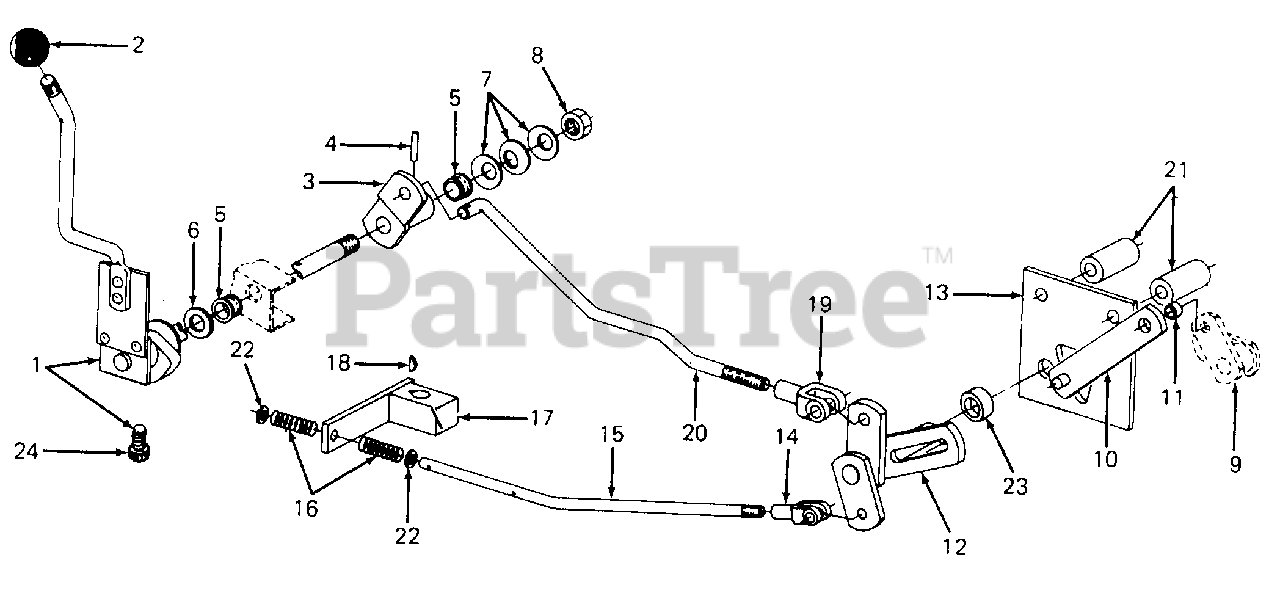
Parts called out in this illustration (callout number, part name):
1	Handle, Shifter Control
2	Knob, Shifter
3	Lever, Shifter
4	Pin, 3/16 X 1 Pln Slt-Spr
5	Bearing, Nyliner
6	Washer, Friction
7	Washer, .760 X 1.50 X .06 Belleville
8	Nut, 1/2 Cad P/T Lock GR 5
9	Control, Brake Link See Brake & Connections, Ref No. 4
10	Link, Actuator
12	Shaft, Hydro Control
13	Plate, Cam
14	Clevis, 5/16-24 X 2-1/4 Pln Lt Adj
15	Rod, Control
16	Spring, Compression
17	Arm Assy, Control Shaft
18	Key, 1/8 X 1/2 SAE 3 Woodruff
19	Clevis, 3/8-24 X 2-1/2 C-Z Lt Adj
20	Rod, Control
21	Spacer, .385 X .88 X 1.88
22	Washer, .385 X .62 X .063
23	Spacer, .635 X .88 X .40
24	Screw, 1/4 X 1/2 Hex-Soc-Hd
